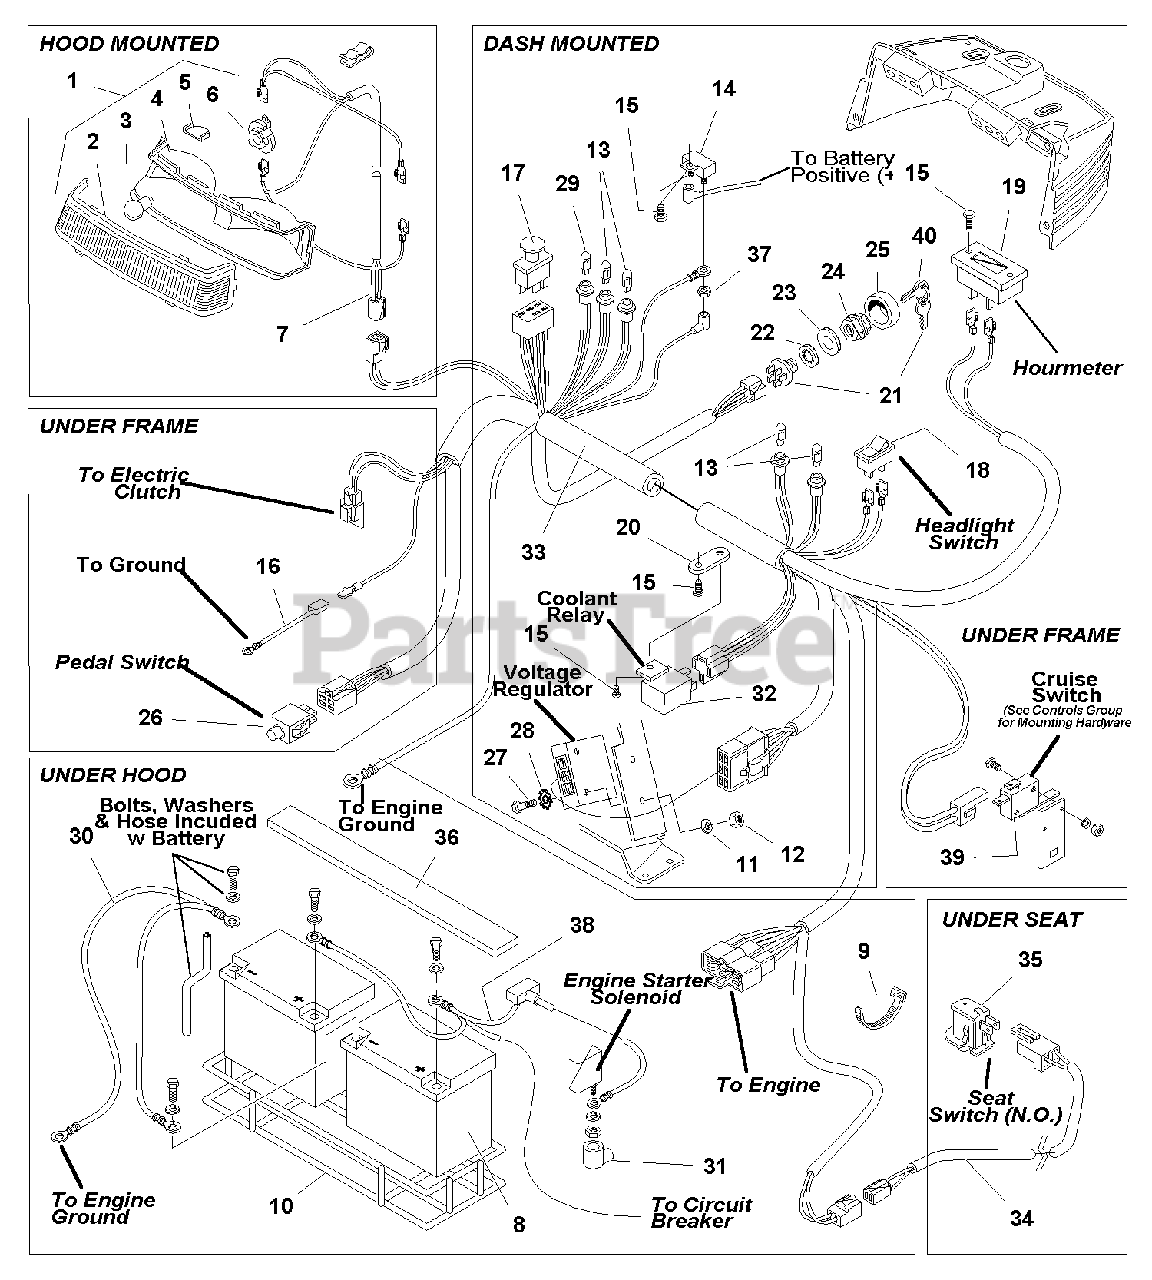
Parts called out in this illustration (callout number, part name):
1	HEADLIGHT ASSEMBLY, Complete (Includes Ref. Nos. 2-6)
2	LENS, Headlight
3	BULB, Headlight
4	BEZEL, Headlight
5	HEAT SHIELD
6	SOCKET, Bulb
7	WIRE ASSEMBLY, Headlight
8	BATTERY KIT
9	TIE, Self-Locking
10	TRAY, Battery, Wireform
11	WASHER, Lock, 1/4
12	NUT, Hex, 1/4-20
13	BULB, Indicator Light
14	CIRCUIT BREAKER
15	CAPSCREW, Hex Head, Plastite, #8-16 x 1/2
16	WIRE ASSEMBLY, Engine Ground
17	SWITCH, PTO Electric Clutch
18	SWITCH, Headlight
20	STRAP, Wire Retainer
21	SWITCH ASSEMBLY, Ignition (Includes Ref. Nos. 22, 23, 24, 25 & 40)
22	WASHER, Lock, Internal Tooth
23	WASHER, 5/8
24	NUT, Hex Flange, 5/8
25	COVER, Key Switch
26	SWITCH, Pedal
27	CAPSCREW, Hex Head, 1/4-20 x 1, G 8
28	WASHER, Tooth Lock
29	BULB, Indicator, Flashing
30	CABLE, Battery Negative to Engine Ground
31	BOOT, Electrical
32	RELAY, Coolant
33	WIRE HARNESS
34	WIRE ASSEMBLY, Seat Switch
35	SWITCH, Seat (NO)
36	COVER, Battery
37	NUT, Hex Flange, #10-32
38	CABLE, Battery (Positive to Engine Solenoid)
39	SWITCH, Interlock
40	KEYS, Set of 2
